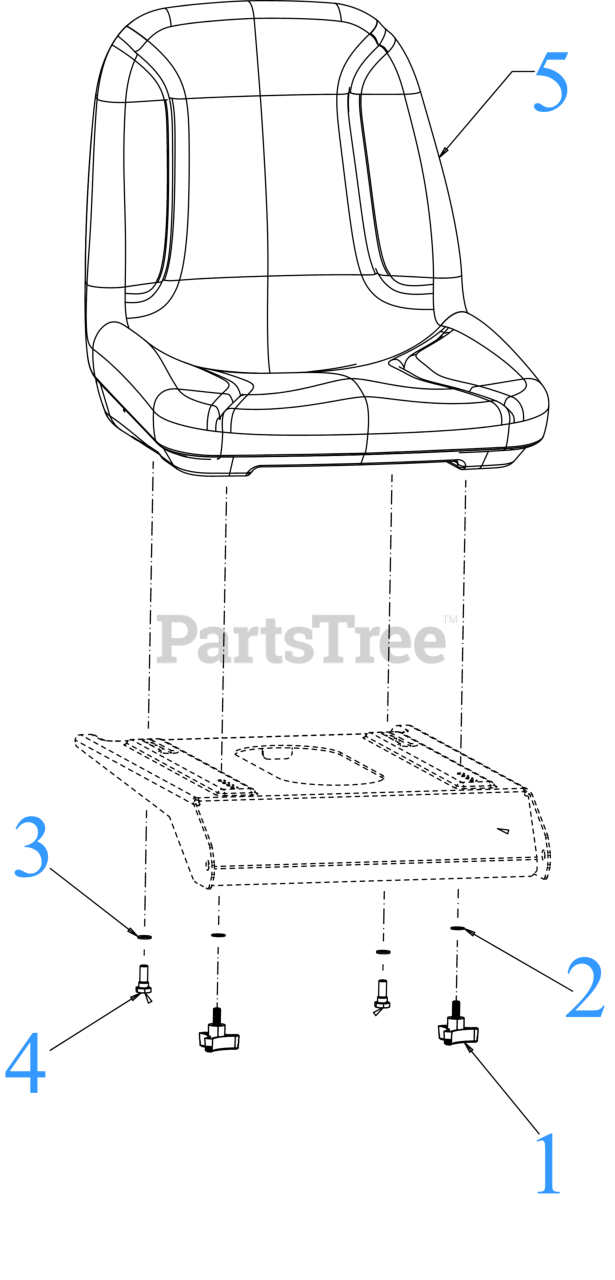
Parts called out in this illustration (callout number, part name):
1	3 PRONG KNOB 5/16-18
2	WASHER
3	FLAT WASHER ID-.320 x .598
4	SHOULDER SCREW .437
5	18" SEAT (4 PT MTG)
